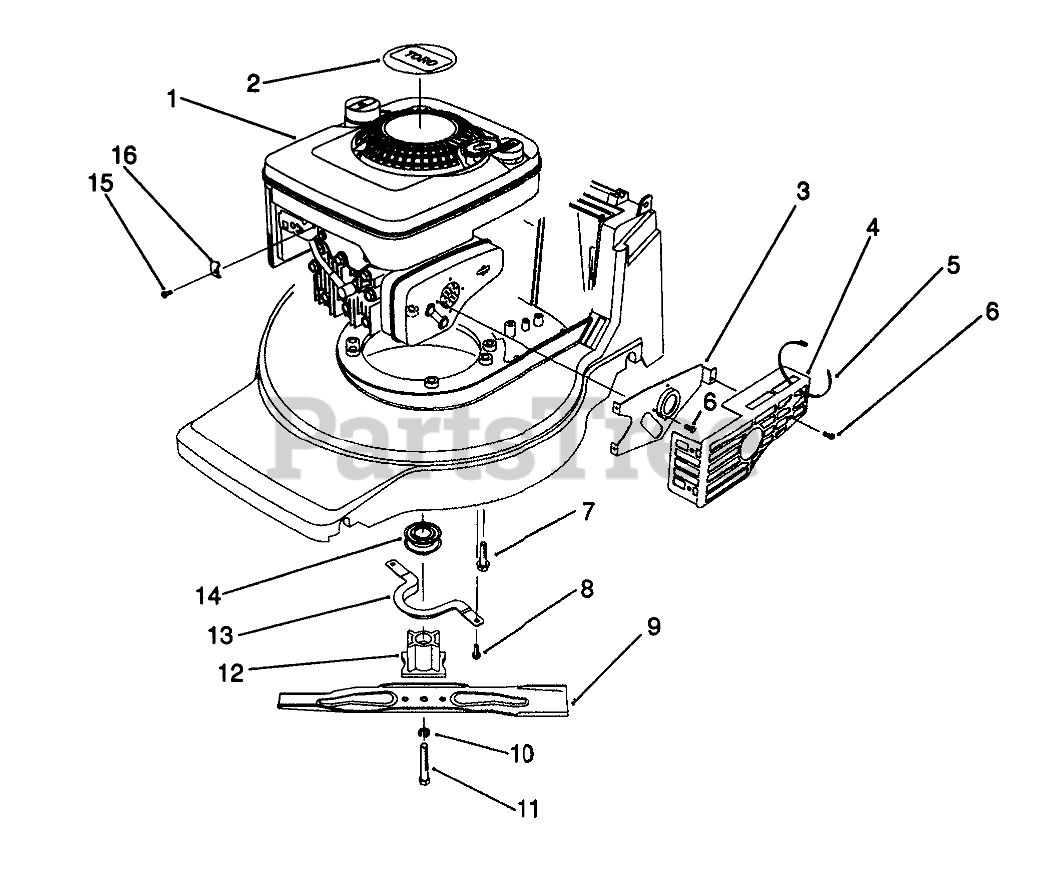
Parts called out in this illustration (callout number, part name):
1	Engine-B&S Quantum
2	DECAL - RECOIL
3	MUFFLER BRKT F/W
4	MUFFLER GUARD F/W
5	TIE-CABLE
6	SCREW W/ENGINE
7	3/8-16 X 2 CAPSCREW
8	SCREW-HWH
9	Blade-48cm
10	WASHER-LOCK
11	BOLT-BLADE
12	BLADE RETAINER - 25 MM
13	Guide-Belt
14	PULLEY-DRIVE, ZONE START
15	Screw
16	CLAMP-CASING
